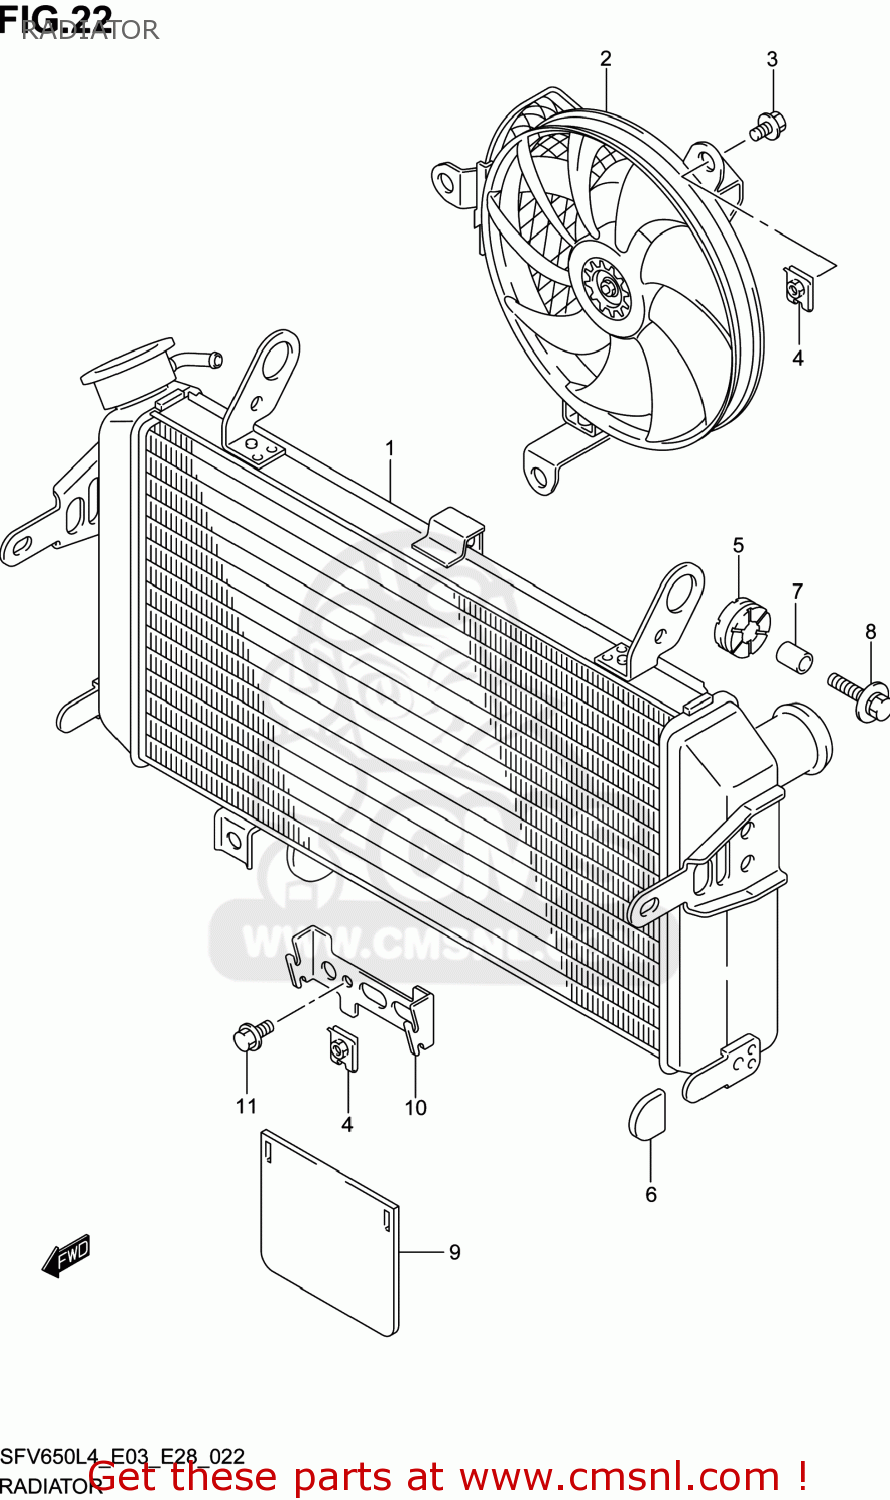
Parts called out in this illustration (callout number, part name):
1	RADIATOR ASSY,WATER
2	FAN ASSY,RADIATOR
3	BOLT,FAN ASSY
4	NUT,FAN ASSY
5	CUSHION
6	CUSHION
7	SPACER(6.5X10X12)
8	BOLT(6X25)
9	RUBBER,RADIATOR UNDER
10	BRACKET,RADIATOR UNDER RUBBER
11	BOLT
